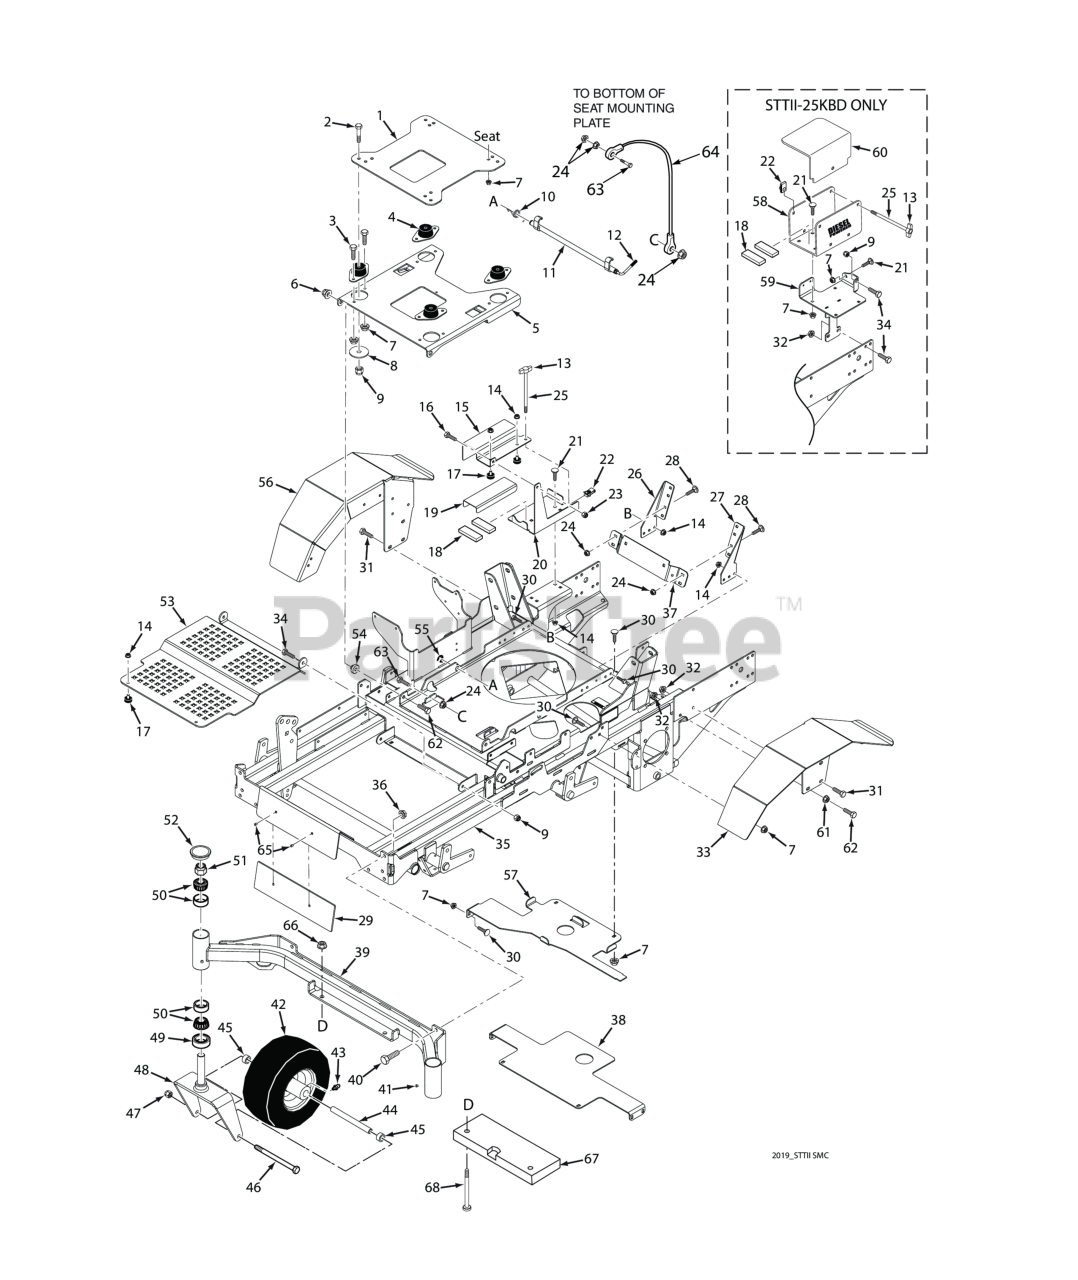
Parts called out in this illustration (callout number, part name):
1	Mounting Plate, Seat w/Decal
2	Bolt, Hex Head 3/8-16 x 2-1/4" - 61"
3	BOLT, SERRATED FLANGE HEX HEAD 5/16-18 X 3/4"
4	Isolator, Seat
5	Seat Mounting Plate, Lower w/Decals
6	Nut, Flange Elastic Stop Nut, 3/8-16
7	Nut, Serrated Flange 5/16-18 (Right Front Engine Mounting, Briggs and Kohler Only)
8	Flatwasher, 3/8-.406 x 2.25" x .1875
9	HEX NUT, ELASTIC STOP LOCK, 3/8-16
10	Spring, Seat Latch
11	Lever Assy., Seat Release
12	Grip, Seat Latch
13	Knob, 1/4" Wing
14	Nut, Serrated Flange 5/16-18 (Right Front Engine Mounting, Briggs and Kohler Only)
15	Cover, Battery Box w/ Decal (Gas & LP)
16	BOLT, SERRATED FLANGE HEX HEAD 5/16-18 X 3/4"
17	Bumper, Rubber 5/16-18 x 5/8"
18	PAD, BATTERY SUPPORT
19	Insulation, Battery Cover (Gas Only)
20	Battery Box (Gas Only)
21	Bolt, 5/16-18 x .75 RHSN Carriage
22	Bolt, Hex Head 3/8-16 x 1"
23	HEX NUT, ELASTIC STOP LOCK, 5/16-18
24	NUT, 1/4-20 SERRATED FLANGE HEX HEAD
25	Bolt, Hex Head 1/4-20 x 8"
26	Mounting Bracket, Cooler - RH
27	Mounting Bracket, Cooler - LH
28	Serr. Fl. Hex Head CPSCR, 1/4-20 x 3/4"
29	Backing Plate
30	Bolt, 5/16-18 x .75 RHSN Carriage
31	Capscrew, 3/8-16 x 1.0" Serrated Flange Hex Hd
32	Threaded Insert, 3/8-16
33	FENDER WLMT, LH
34	Bolt, Hex Head, 3/8-16 x 1 Gr. 5
35	Mainframe Assy., w/Decals
36	Nut, 7/16-14 Flange Elastic Stop
37	Bracket, Carbon Canister
38	Front Support, Fuel Tank
39	Caster Support Weldment - 72V
40	BOLT, HEX HEAD, 7/16-14 X 1-1/4
41	Plug, 1/4-28 THD Form
42	Wheel Assy, 61V, 72V (Incl. 20, 54, 55)
43	Grease Fitting
44	Sleeve, Caster Wheel (61V, 72A/VS)
45	Spacer, Caster Wheel
46	Bolt, Hex Head 1/2-13 x 9-1/2" (61V & 72A/VS)
47	HEX LOCKNUT, ELASTIC STOP, 1/2-13
48	Yoke Weldment
49	Seal, 2.00" O.D. x 1.625" Bore
50	BEARING & CUP, TAPERED SPINDLE
51	Nut, Hex Elastic Stop 1.0"-14
52	Cap, Grease
53	Foot Plate
54	Sleeve, Seat Base Mounting
55	RETAINING RING, 5/8" EXTERNAL "E"
56	Fender, RH
57	Rear Support, Fuel Tank
58	Battery Box w/Decal (Diesel Only)
59	Battery Bracket Weldment (Diesel Only)
60	Cover, Battery (Diesel Only)
61	NUT, 3/8-16 SERRATED FLANGE HEX HEAD
62	Bolt, Hex Head, 3/8-16 x 1-1/2"
63	SERR. FLG. HEX HEAD CAPSCREW, 5/16-18 X 3/4
64	CABLE, SEAT STOP
65	Rivot, 3/16 x .402 POP
66	Nut, Hex Serrated Flange 1/2-13
67	Weight (61" cutter deck only)
68	CAPSCREW, 1/2-13 X 4.00 FHHS
